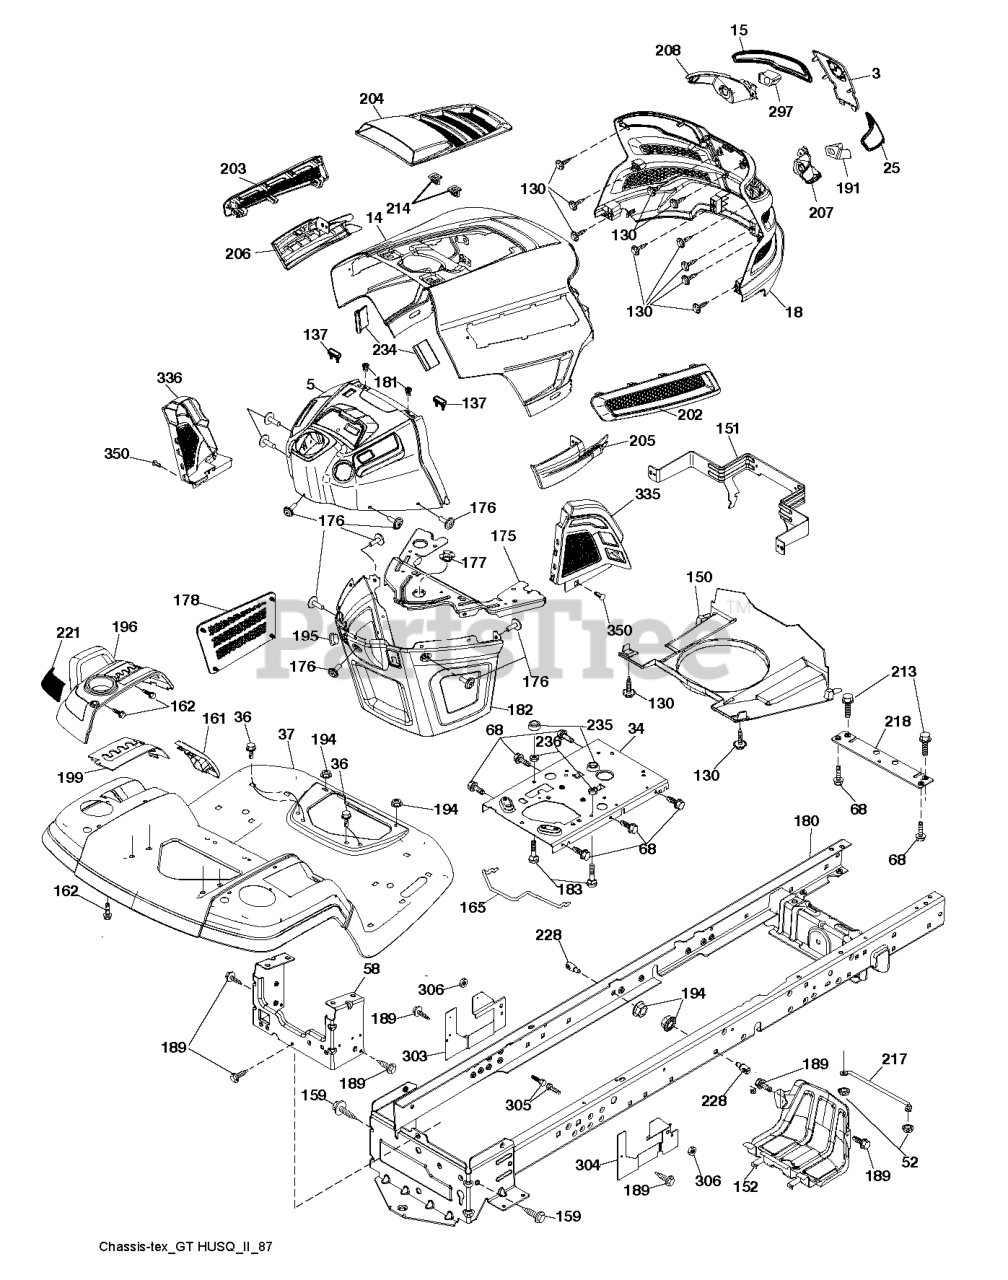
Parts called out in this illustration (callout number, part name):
3	APPLIQUE.SUBASM.GT.HUSQ.II
5	DASH.UPP.GT2.SM.PTO.MCHOKE
14	HOOD.ASM.HUSQVARNA.GT.TEX.ORAN
15	LENS.HEADLIGHT.LH.GTII.2011
18	GRILLE.SUBASM.GT.HUSQ.II
25	LENS.HEADLIGHT.RH.GTII.2011
34	PLATE.ENGINE.WELDED.CHASSIS
36	SCREW 5/16"
37	FENDER.PNT.TX.GT.CH/FW.ORANGE
52	LOCKNUT
58	DRAWBAR.UPPER.2PC,LRG.FENDER
68	Screw 5/16-18 x 1/2 Hex, Self Tapping 5/16-18 x 1/2
130	SCREW.#10 X 0.750.BOS
137	BUMPER DASH
150	AIR.DUCT.GTV.BLACK
151	BRACKET.PIVOT.HOOD.GT.HUSQ.II
152	SHIELD.BROWNING.PNT.GT.V2
159	SCREW, 3/8-16X3/4
161	CONSOLE.FUEL.WINDOW.HU
162	SCREW.HI-LO.CONSOLE
165	SUPPORT.TANK.REAR.W/TEX
175	PLATE.CROSSMEMBER.HUSQ
176	SCREW.#10-24X5/8.RN.QU
177	BUSHING, STEERING
178	CARGO.ASM.NET.TXGT.W/C
180	CHASS.WLDMNT.TLT.12GA/2PC.20"
181	BUSHING.MNT.FEND.CRGO.
182	DASH.LOWER.COMMON.12V.ADAPTOR
183	BOLT.5/16-18X1-1/4 FULL THD
189	SCREW
191	INSERT.REFLECTIVE.RH.HUSQ.GTII
194	NUT LOCK HEX FLANGE 5/16-18
195	PLUG.HOLE.DASH.LOWER.12V.BLK
196	RP CONSOLE.ASM.DECKLFT.W/
199	PLATE.DECK.LIFT.HUSQVARNA.GT
202	VENT.SIDE.RH.GT.HUSQ.II.
203	VENT.SIDE.LH.GT.HUSQ.II.498
204	VENT.TOP.HUSQ.GT2
205	SIDE.TRIM.RH.GT.HUSQ.II
206	SIDE.TRIM.LH.GT.HUSQ.II.GRAY
207	BEZEL LIGHT.RH.GT.II.MYLAR
208	BEZEL LIGHT.LH.GT.II.MYLAR
213	BOLT
214	CLIP.RETAINER.TINNER.
217	ROD.PIVOT.HOOD
218	X-PIECE.HOOD.STOP.NON/
221	REFLECTOR.LH.TEX GT HU
228	STUD.FASTNER.W/ANTI-ROTATE
234	BUMPER.HOOD.TEX.HUSQVARNA
235	SPACER FENDER
236	NUT.CENTERLOCK.5/16-
297	INSERT.REFLECTIVE.LH.HUSQ.GTII
303	SHIELD CHASSIS LEFT
304	SHIELD CHASSIS RIGHT
306	NUT LOCK FLG 3/8-16 UNC
335	COVER.LOWER.DASH.RH.BLACK
336	COVER.LH.CLOSE.OUT
350	CLIP.X-MAS.TREE
